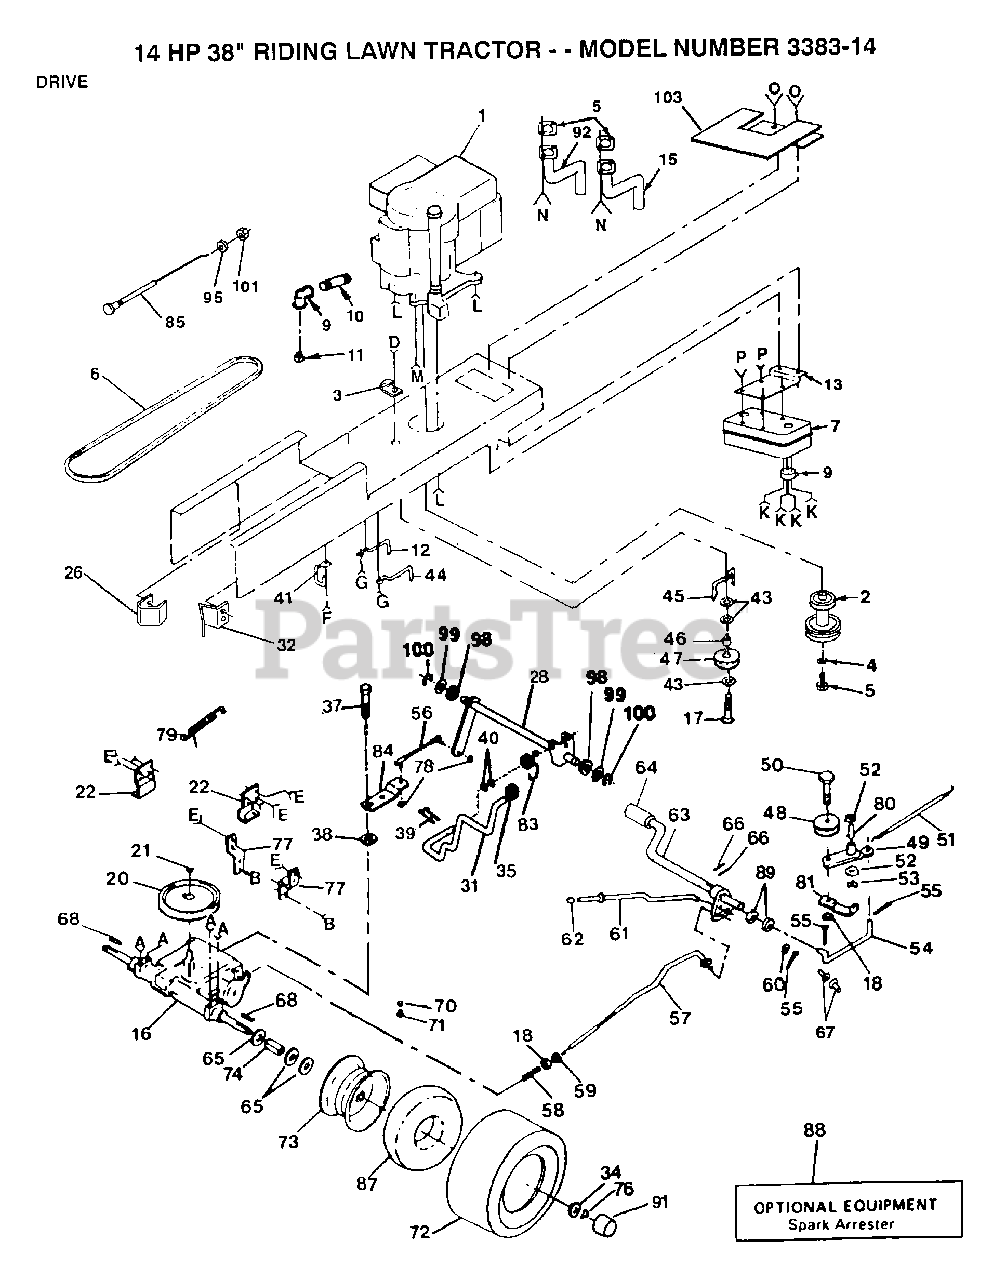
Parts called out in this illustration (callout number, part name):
3	CLIP T
4	LOCKWASHER
5	BOLT
6	BELT-V.90.0.GD.DR
7	MUFFLER
9	DEFLECTOR.222573
10	PIPE NIPPLE LT
12	TUBE ASSY EXH LH
13	BRACKET MUFFLER
15	TUBE ASSY EXH RH
17	BOLT
18	NUT
20	PULLEY TRANS
22	BRACKET LT
26	"KEEPER,BELT LH T"
28	"SHAFT,SHIFTER "
32	"KEEPER,BELT RH T"
34	WASHER
35	KNOB T (1/2-HOLE)
38	WASH-SHFT PLT LT
39	PIN COTTER 1/8
40	WASHER
43	WASHER
44	"KEEPER,BLT ENG LT"
45	BELT KEEPER LT
46	SPACER T
47	PULLEY.IDLER.FLAT
49	ARM IDLER
51	"SPRING, RETURN LT"
52	WASHER LT
53	KLIP RING
54	"LINK, CLUTCH T"
55	COTTER PIN
56	"ROD,TIE "
57	BRAKE ROD LT
58	SPRING ROD LT
59	NUT
60	WASHER
62	PLUNGER CAP T
64	PEDAL COVER T
65	WASHER
67	NYLON BEARING
68	SQUARE KEY
70	VALVE CAP
71	VALVE STEM LT
74	SPACER LT
76	E-RING LT
77	STRAP TORQUE
78	NUT 1/4-28
80	"LY, BEARING"
81	RETAIN BELT
83	"SPRING,TORSION"
84	"ARM,SHIFT"
87	TUBE.18X9.5-8
88	SPARK ARREST KIT
89	WASHER LT
91	HUB CAP
95	LOCKWASHER
98	"BUSH,PIVOT T"
99	"WSHER,SHIM"
100	RING T
